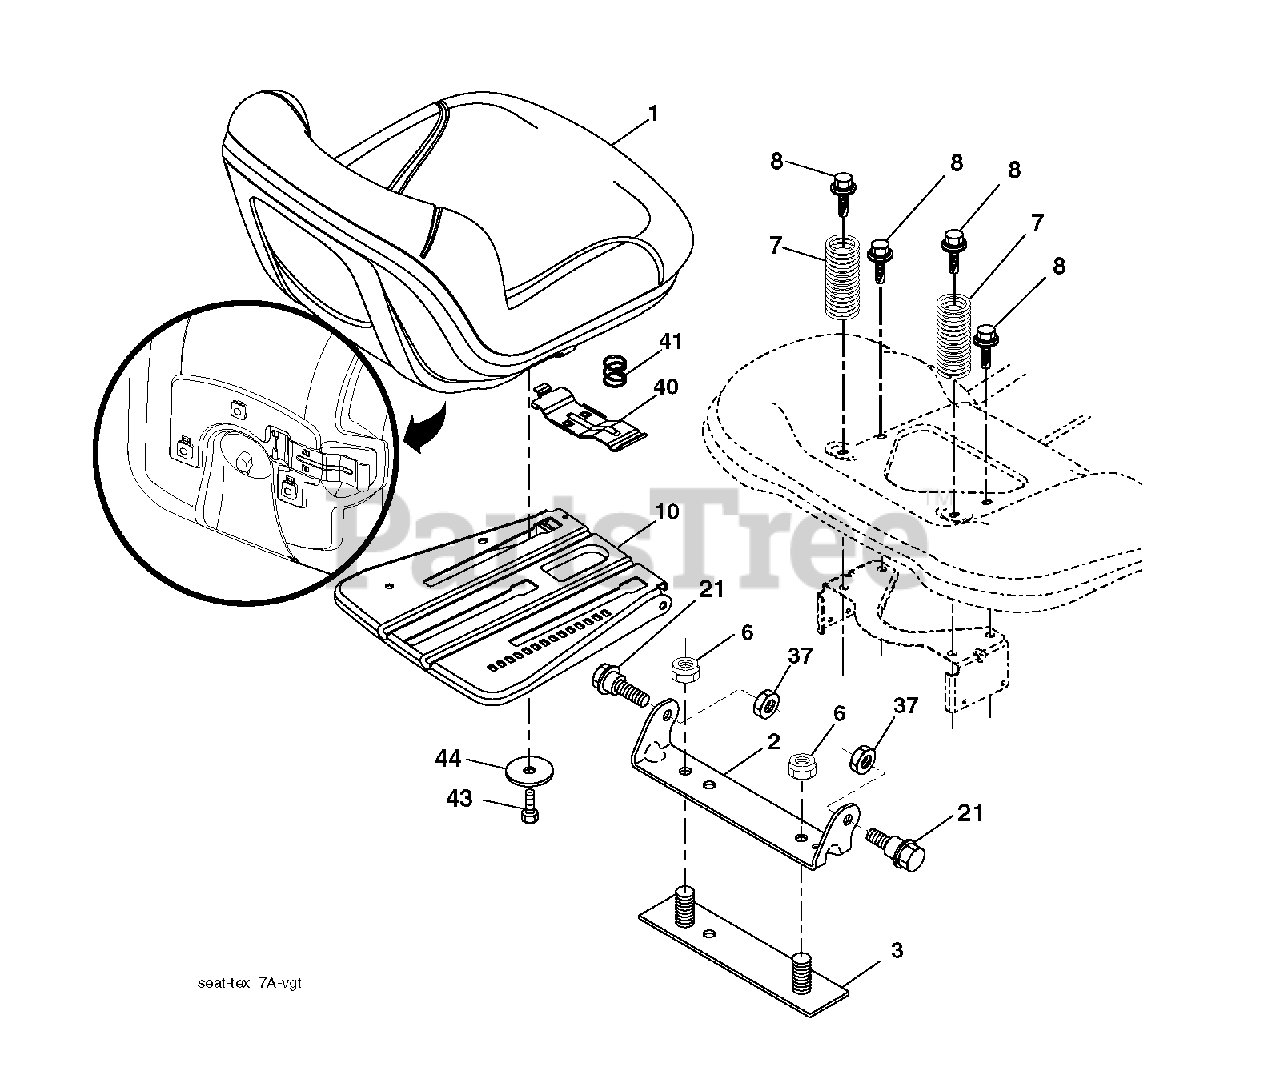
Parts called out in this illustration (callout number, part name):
1	SEAT.TG130.BLACK.NO/LOGO.
2	BRKT.PIVOT.FENDER
6	NUT
7	SPRING COMPRESSION
8	BOLT, 5/16-18 X 1 3/4
10	PAN.ASM.SEAT.3PT
21	BOLT.SHOULDER.5/16-18
37	NUT.71038.31-18.HEX.NYLOCK
40	HANDLE.SLIDE.SEAT.TEX.BLACK
41	SPRING.LATCH.SEAT.TEX
44	WASHER 13/32 X 2-3/8 X 12GA
